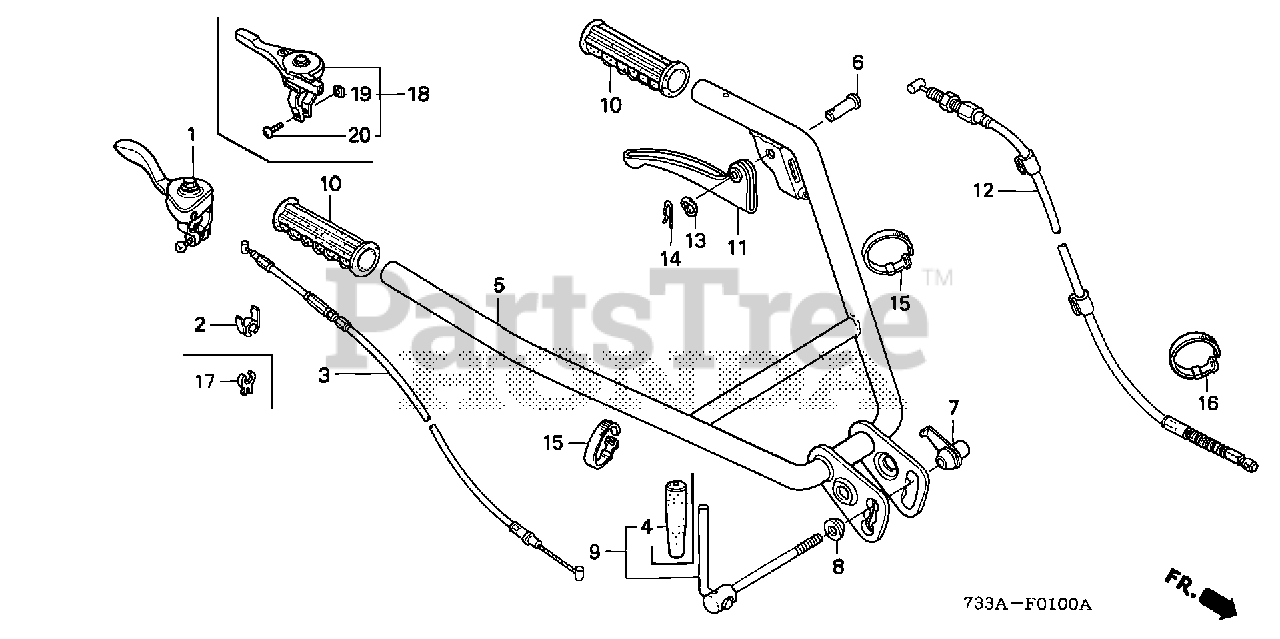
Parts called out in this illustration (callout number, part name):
3	CABLE, THROTTLE
5	PIPE, HANDLE (CHROME PLATED)
5	PIPE, HANDLE (BLACK)
6	PIN, EXCHANGE (8X21)
7	NUT, HANDLE LOCK
8	NUT, SPECIAL
9	LEVER, HANDLE ADJUSTING
10	GRIP, R. HANDLE
11	LEVER, CLUTCH
12	CABLE, MAIN CLUTCH
14	PIN, SNAP (7MM)
15	BAND, CABLE (120MM) (BLACK)
16	BAND, SUCTION HOSE (BLACK)
17	CLIP, THROTTLE (RESIN MOLDED CLIP)
18	LEVER ASSY., THROTTLE (RESIN MOLDED LEVER)
19	NUT, SQUARE (5MM)
20	SCREW, PAN (5X20)
